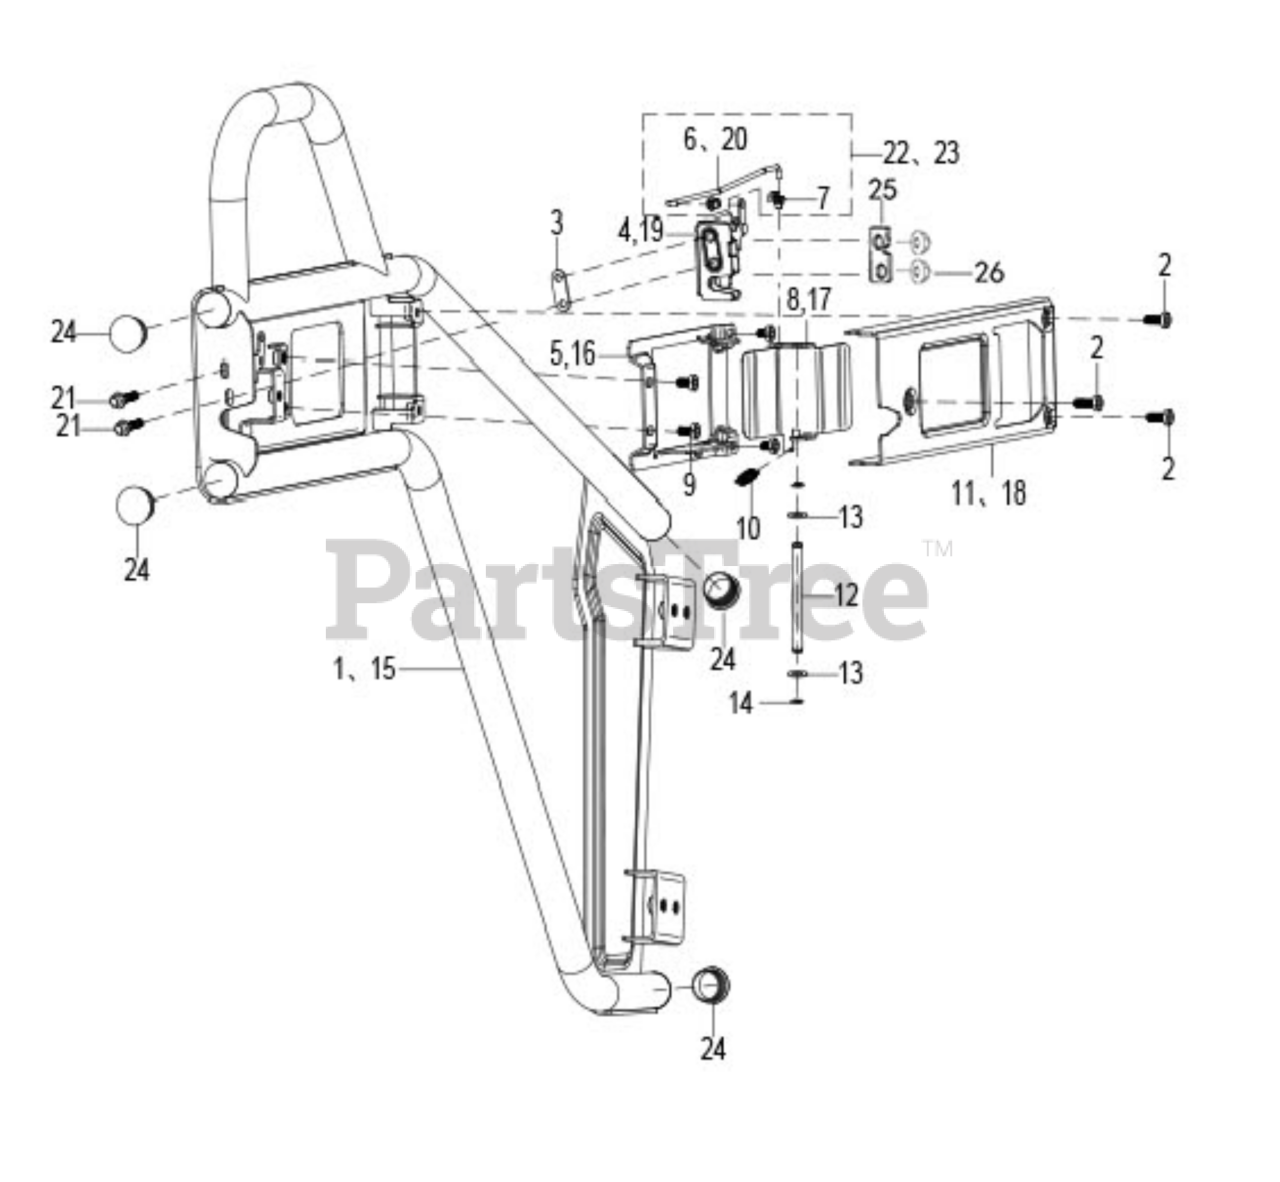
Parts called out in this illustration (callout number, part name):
1	DOOR ASM (LH)
2	SOCKET HEX FLAT HEAD BOLT M6X16
3	DOOR LOCK ADJUSTMENT GASKET
4	DOOR LATCH (LH)
5	LOCK MOUNTING PLATE (LH)
6	LOCK ROD (LH)
7	PLASTIC ROD CLIP
8	DOOR HANDLE (LH)
9	FLANGED HED HEAD BOLT M6X8
10	TENSION SPRING
11	LOCK MOUNT PLATE (LH)
12	SLOTTED ROD 8 X 91
15	DOOR ASM (RH)
16	LOCK MOUNT PLATE (RH)
17	DOOR HANDLE (RH)
18	LOCK MOUNT PLATE (RH)
19	DOOR LATCH (RH)
20	LOCK ROD (RH)
21	HEXAGON FLANGE BOLT M6X35
22	LOCK ROD (LH)
23	LOCK ROD (RH)
24	ROUND PLASTIC PLUG
25	LOCK REINFORCEMENT PLATE
26	LOCK NUT M6
